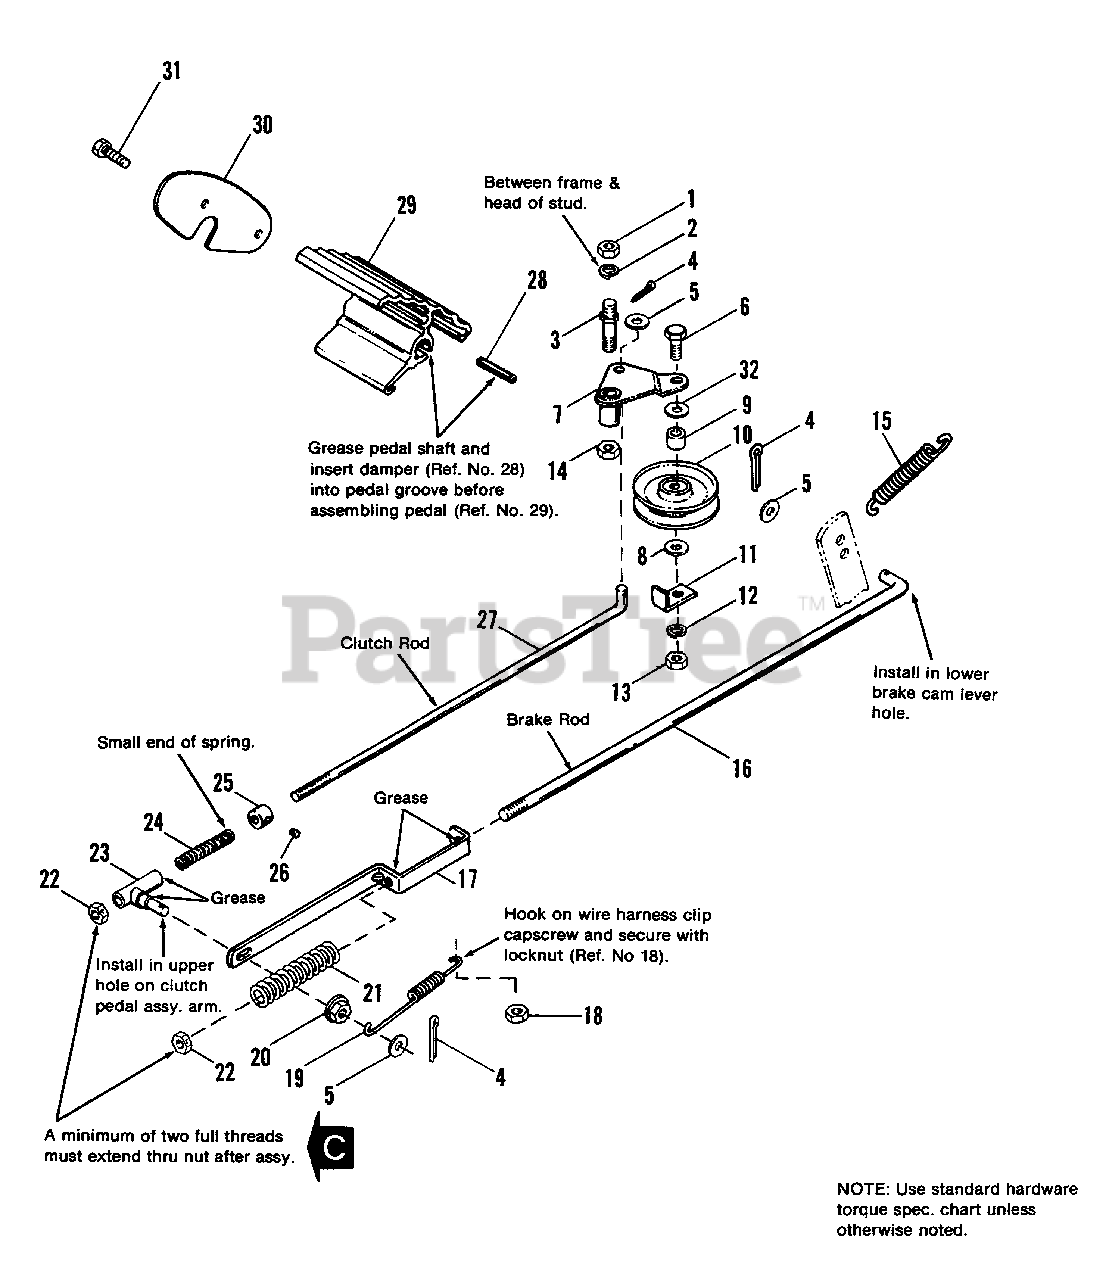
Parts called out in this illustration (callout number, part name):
1	NUT, Hex, 7/16-14
2	LOCKWASHER, 7/16
4	PIN, Cotter, 3/32 x 3/4
5	WASHER, 1/4
6	CAPSCREW, 3/8-16 x 1-1/2
7	IDLER ASSY.
8	WASHER, Plain, 5/16
10	PULLEY ASSY.
11	GUIDE, Belt
12	LOCKWASHER, 3/8
13	NUT, Hex, 3/8-16
14	LOCKNUT, Hex, 7/16-14
15	SPRING, Tension
18	LOCKNUT, Hex, 5/16-18
19	SPRING, Return
20	LOCKNUT, Hex, Flange, 5/16-18
22	LOCKNUT, 5/16-18
23	GUIDE ASSY., Rod
24	SPRING, Compression
25	COLLAR, Set
26	SETSCREW, 1/4-20 x 3/8
27	ROD, Clutch
28	DAMPER, Rubber
29	PEDAL, Foot
30	PLATE, End
31	SCREW, Taptite, 1/4-20 x 5/8
32	WASHER, Plain
